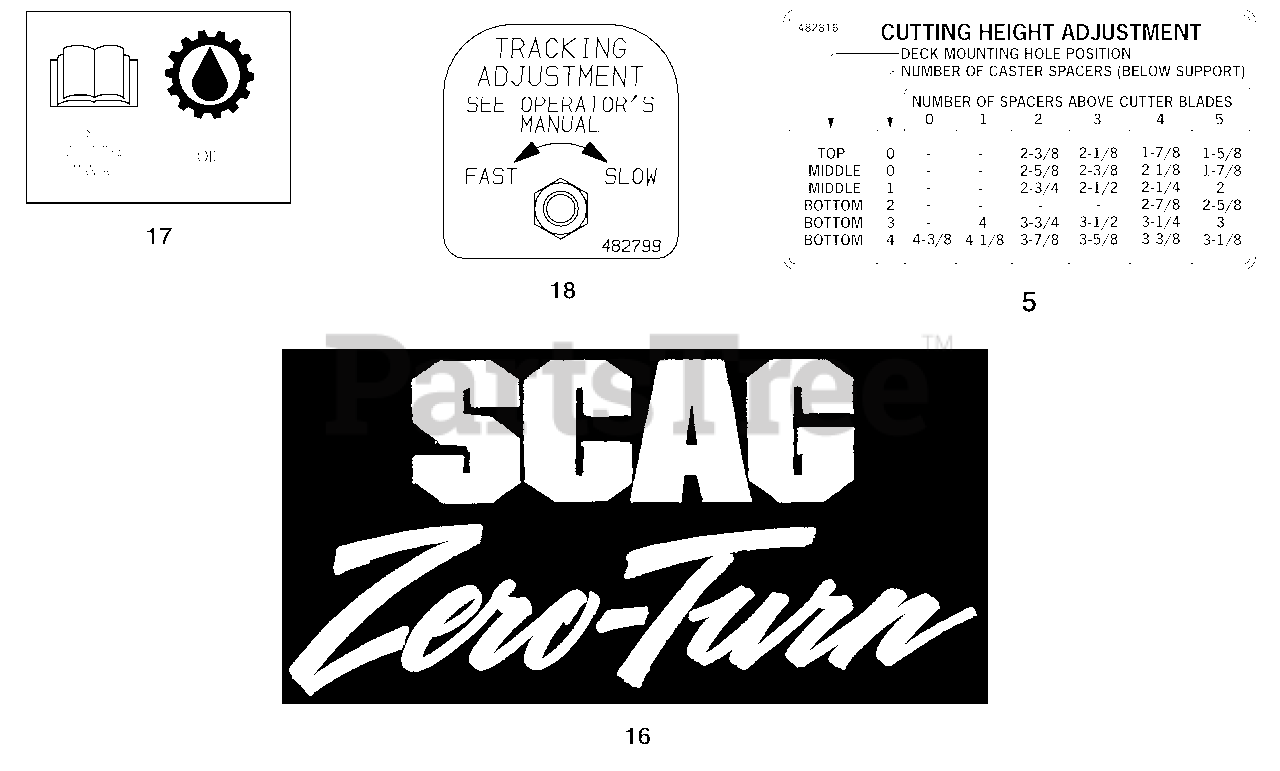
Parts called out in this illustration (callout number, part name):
5	Decal, Height of Cut
16	Decal, Scag Zero Turn
17	Decal, Oil
18	Decal, Tracking Adjustment
